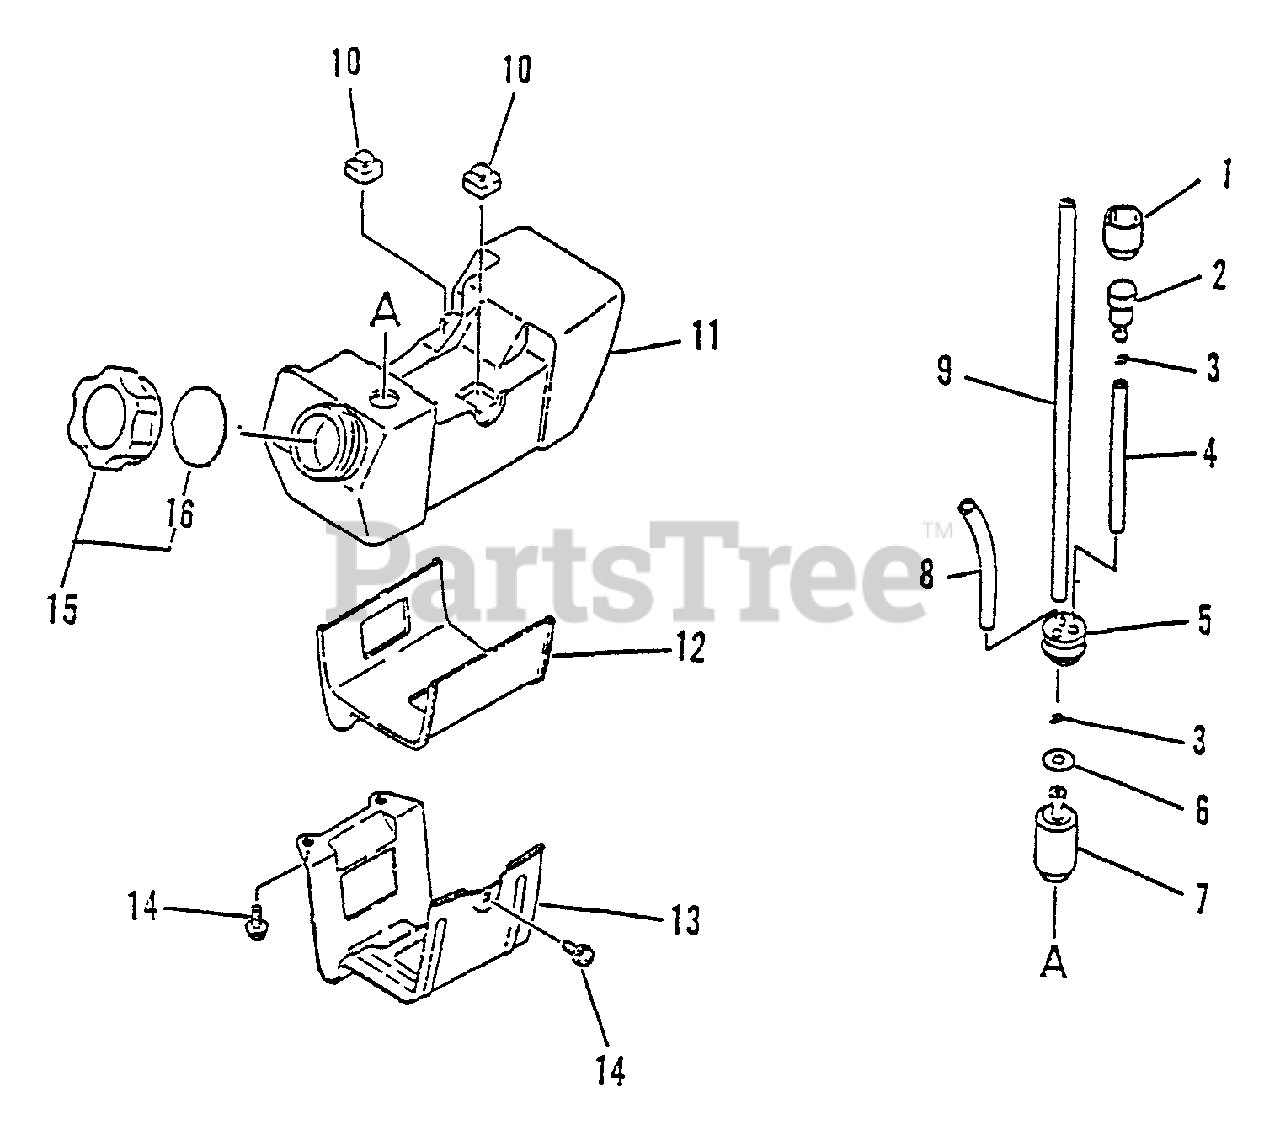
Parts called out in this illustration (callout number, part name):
1	HOLDER, VENT
2	VENT ASSY
4	PIPE, FUEL VENT 3×5×60
5	GROMMET, FUEL
6	WASHER 5.5×12×0.8
7	FILTER, FUEL
8	PIPE, FUEL RETURN 3×6×90 MM CLEAR
9	PIPE, FUEL 3x-5x-180
10	CUSHION
11	TANK, FUEL
12	CUSHION
13	GUARD, FUEL TANK
14	SCREW 5×10
15	CAP ASSY
16	GASKET, FUEL CAP
